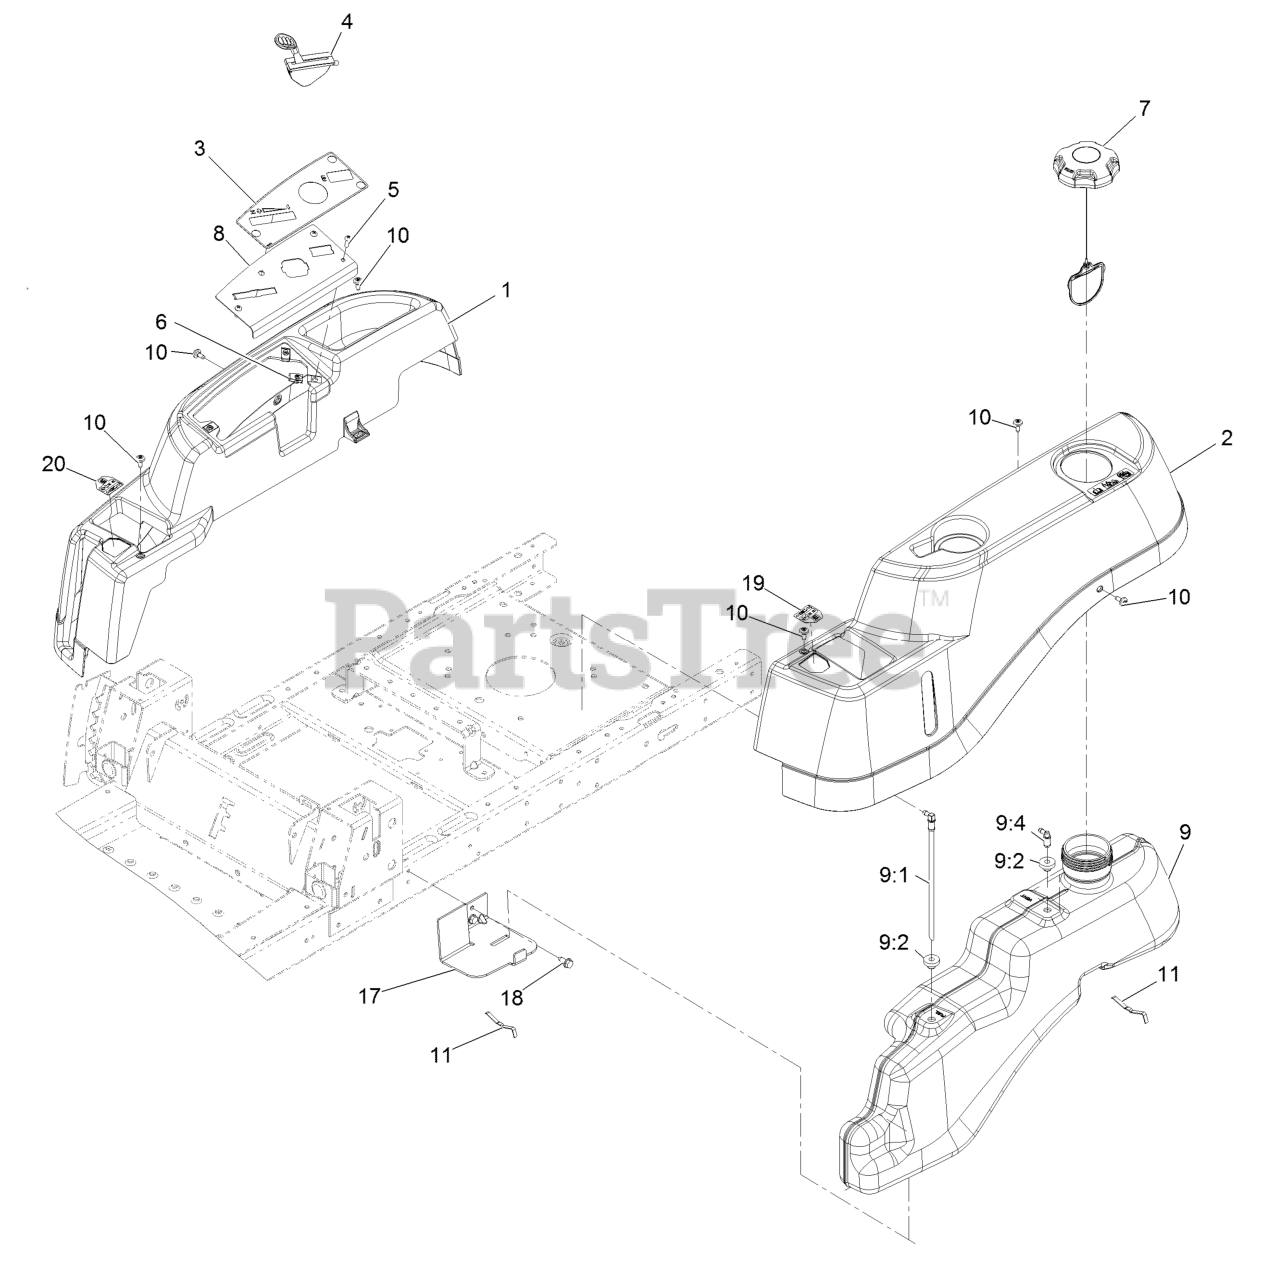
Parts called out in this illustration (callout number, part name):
3	DECAL-PANEL, CONTROL
4	CABLE-THROTTLE AND CHOKE
5	SCREW-PRH
6	Nut-Retainer-Panel 1/4-20
8	PLATE-CONTROL
9	FUEL TANK ASM
9:1	CONNECTOR-ELBOW, 90 DEG
9:2	BUSHING
9:4	FITTING-PLASTIC
10	SCREW-SHOULDER
11	SPRING
17	SUPPORT-TANK, FRONT
18	Screw-HWH 5/16-18 X 3/4 Tf
19	DECAL-LEVER, CONTROL (LH)
20	DECAL-LEVER, CONTROL (RH)
